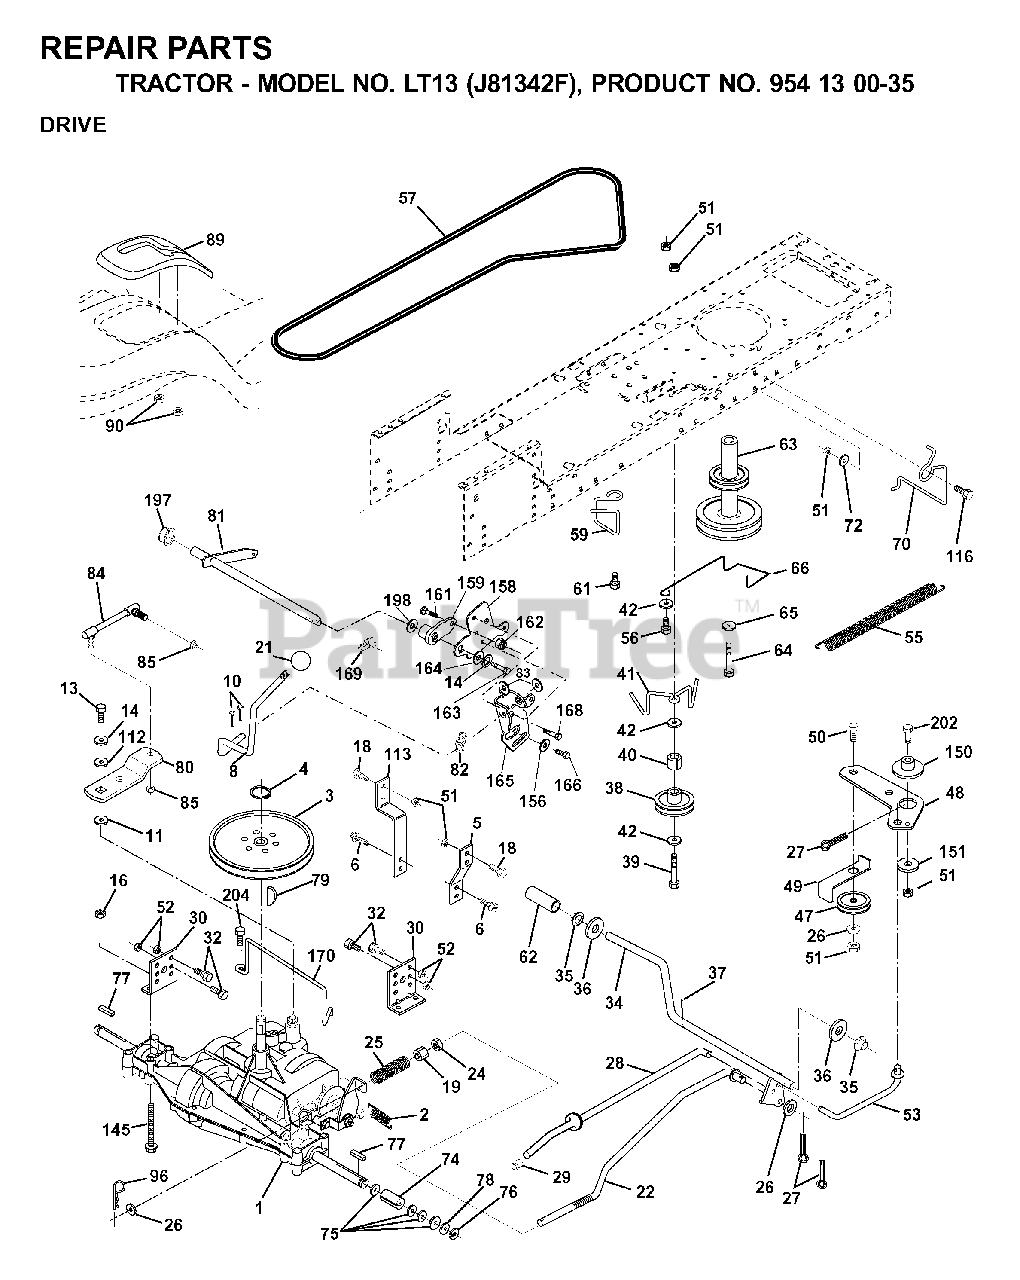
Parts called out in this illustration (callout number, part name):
2	SPRING,BRAKE RETURN
3	PULLEY TRANS
4	RETAINING RING LT
5	STRAP TORQUE
6	SCREW
8	ROD SHIFT FENDER ADJUST STLT
10	PIN COTTER
11	WASH-SHFT PLT LT
13	BOLT 1/4-28X3/4
14	LOCKWASHER
18	BOLT
19	NUT
21	KNOB.DELUXE.(PISTOL.GRIP).BLAC
22	ROD BRAKE
24	NUT
25	SPRING ROD LT
27	COTTER PIN
28	ROD BRAKE PARK LT
29	PLUNGER CAP
30	BRACKET TRANSAXLE
32	BOLT
34	SHAFT, FOOT PEDAL
35	BEARING.NYLON
36	WASHER LT
37	DRIVE PIN
38	FLAT IDLER PULLEY
41	KEEPER.BELT.IDLER.FLAT
42	WASHER
47	IDLER PULLEY
48	BELLCRANK, CLUTCH
49	RETAIN BELT
50	BOLT
51	LOCKNUT
52	LOCKNUT
53	LINK, CLUTCH LT
55	SPRING, RETURN LT
59	KEEPER, BELT CENTER
61	SCREW 5/16"
62	PEDAL COVER T
63	PULLEY ENGINE
64	BOLT
65	LOCKWASHER
66	KEEPER BELT ENGINE
70	KEEPER BELT ENG
74	SPACER AXLE
76	E-RING LT
77	SQUARE KEY
80	ARM SHIFT
82	SHIFT SPRING
83	WASHER
85	NUT LOCK CENTER 1/4 -28 FNTHD
89	CONSOLE.SHIFT.STLT.6SP.BLACK
96	RETAINER M
112	WASHER LT
113	STRAP TORQUE LH LT
116	BOLT
145	BOLT
150	BUSHING.BELLCRANK.GRD.DR
151	WASHER 12/32X2X10GA
156	WASHER.SRRTD.5/16
158	BRACKET
159	HUB
161	BOLT
162	NUT.CROWNLOCK.1/4
163	BOLT
165	RP BRACKET
168	BOLT.SHOULDER.5/16-18X
169	PLATE.FASTENING.CROSS.SHAFT
197	NYLINER SNAP 5/8" ID
198	WASHER.NYL.7/8IDX.105"HYD CR
202	BOLT.3/8-16X1.50
204	SCREW 5/16-18X1
